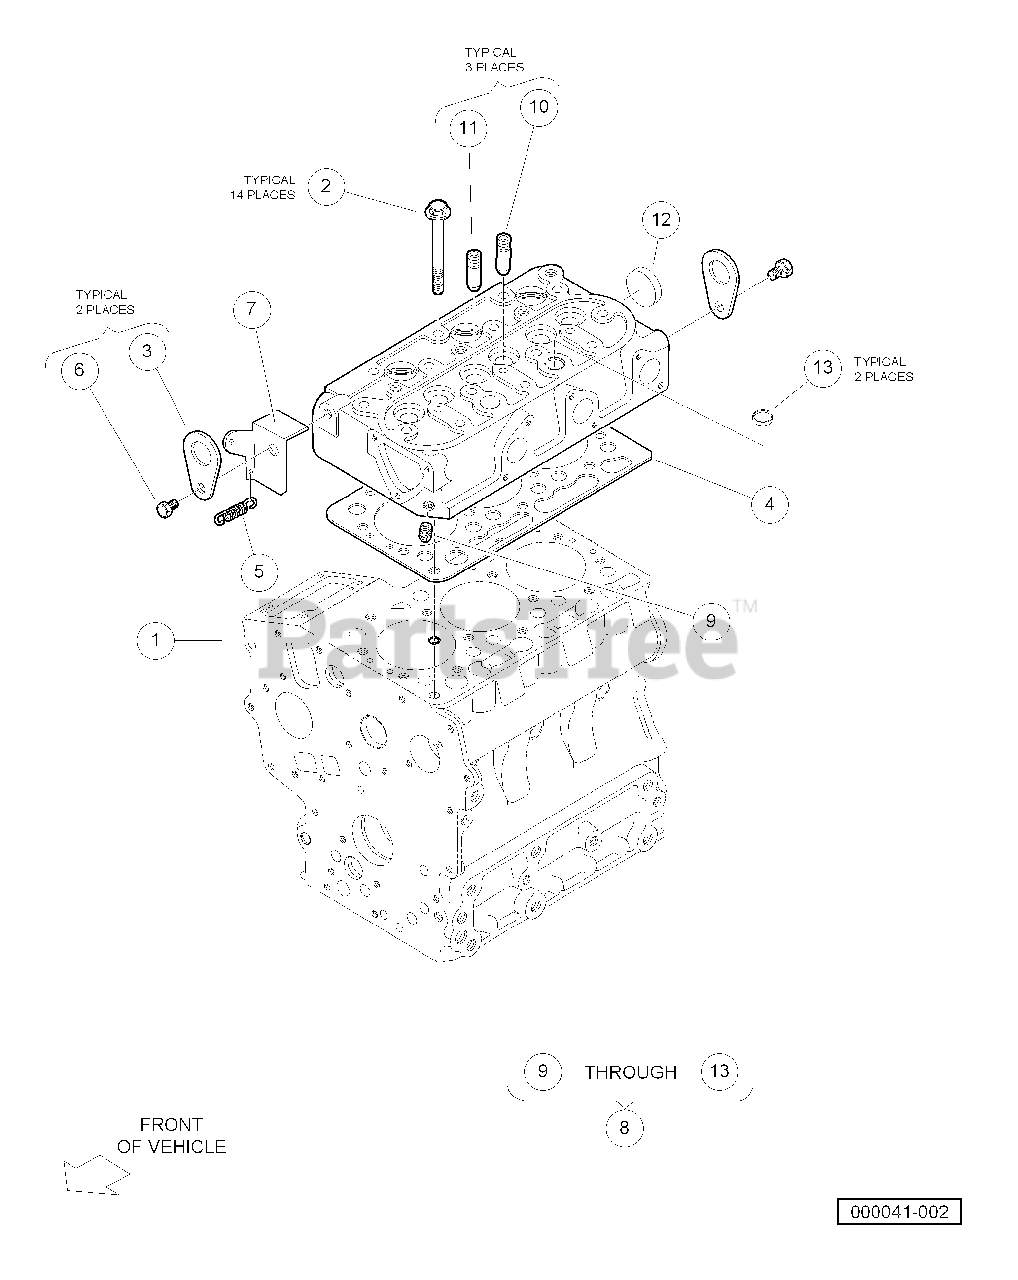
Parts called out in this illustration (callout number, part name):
1	O Ring, 8 X 7
2	Bolt, Cylinder Head
3	Hook, Engine
4	Gasket, Cylinder Head
5	Spring, Start
6	Bolt, Engine Hook
7	Stay, Cylinder Head
8	Head, Cylinder, Complete
9	Plug, 3/32"
10	Guide, Exhaust Valve
11	Guide, Inlet Valve
12	Cap, Sealing, Head
13	Cap, Sealing, Head, Top
